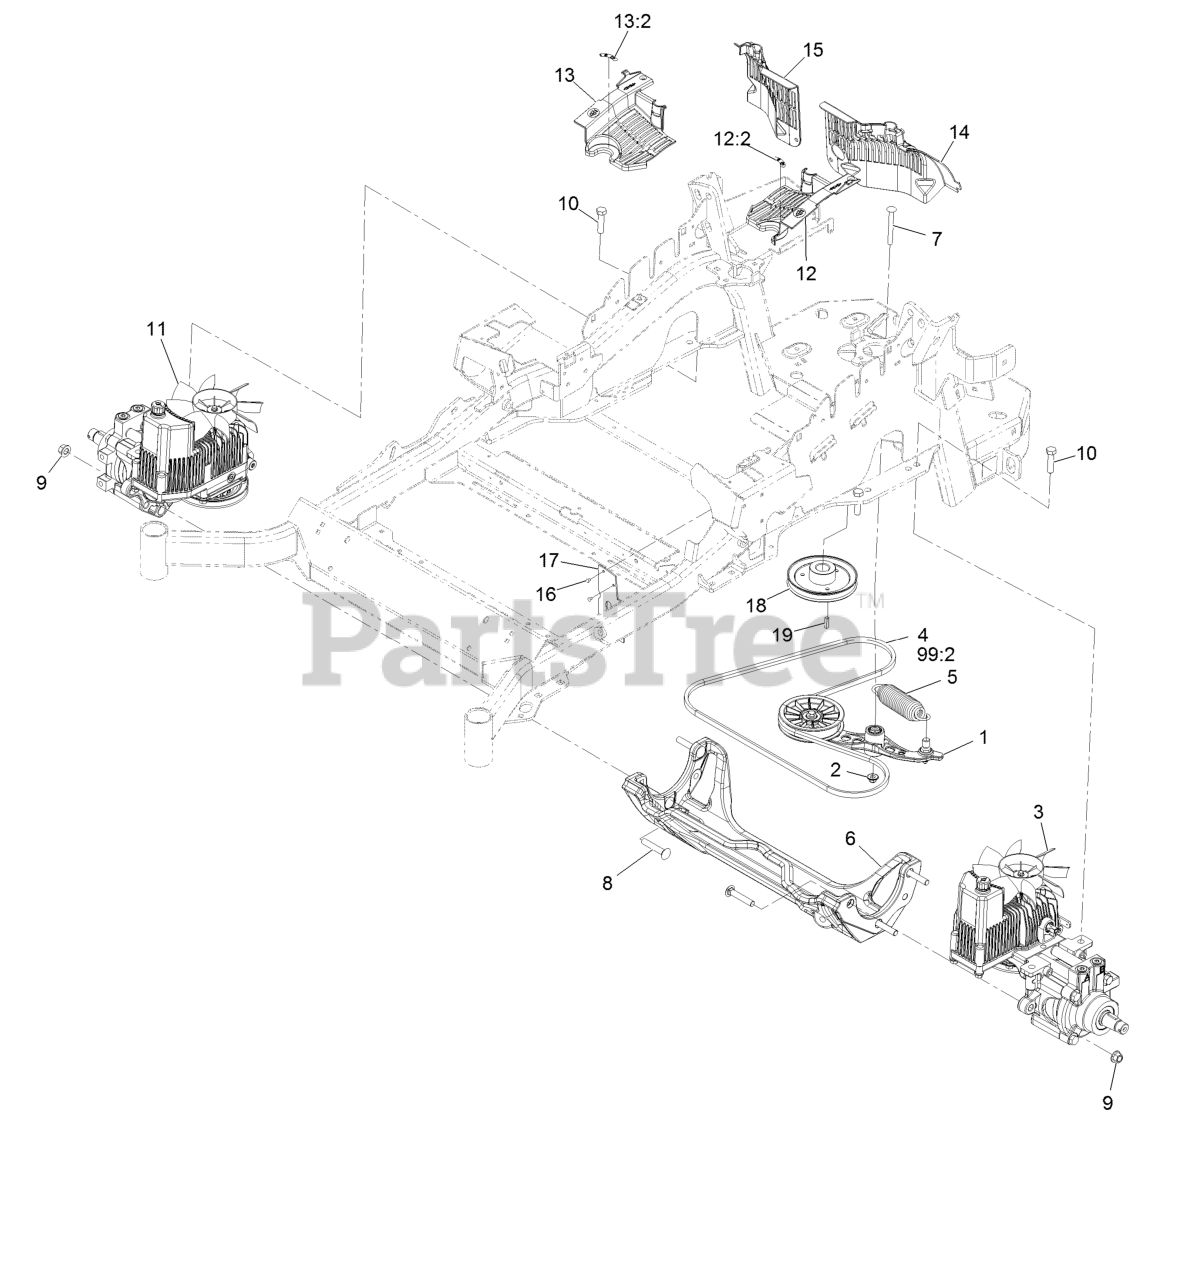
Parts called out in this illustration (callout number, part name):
1	Pump Idler ASM
2	Nut-Nyloc 3/8-16 Flg
3	LH Hydro ASM (12Cc W/Shock)
4	Belt
5	Spring-Extension
6	Cradle-Hydro
7	Bolt-Carriage Shoulder 3/8-16 X 3 1/2
8	Screw-CARR
9	Nut-Lock 1/2-13
10	Screw-HH 1/2-13 X 1 1/4
11	RH Hydro ASM (12Cc W/Shock)
12	LH Hydro Guard ASM
12:2	Decal-Oil, Hydro
13	RH Hydro Guard ASM
13:2	Decal-Oil, Hydro
14	Guard-Hydro, Rear (LH)
15	Guard-Hydro, Rear (RH)
16	Rivet 3/16 X 1/4
17	Deflector-Air Flow
18	Sheave
19	Key-Machine 1/4 X 1/4 X 1
99	Bottle-Oil, 32Oz Hydraulic
99	Filter-Hydro
99	Bottle,Oil 1 Gallon Hydraulic
99	Kit, Hydro Service
99:1	Bottle-Oil, 32Oz Hydraulic
99:2	Belt
99:3	Filter-Hydro
